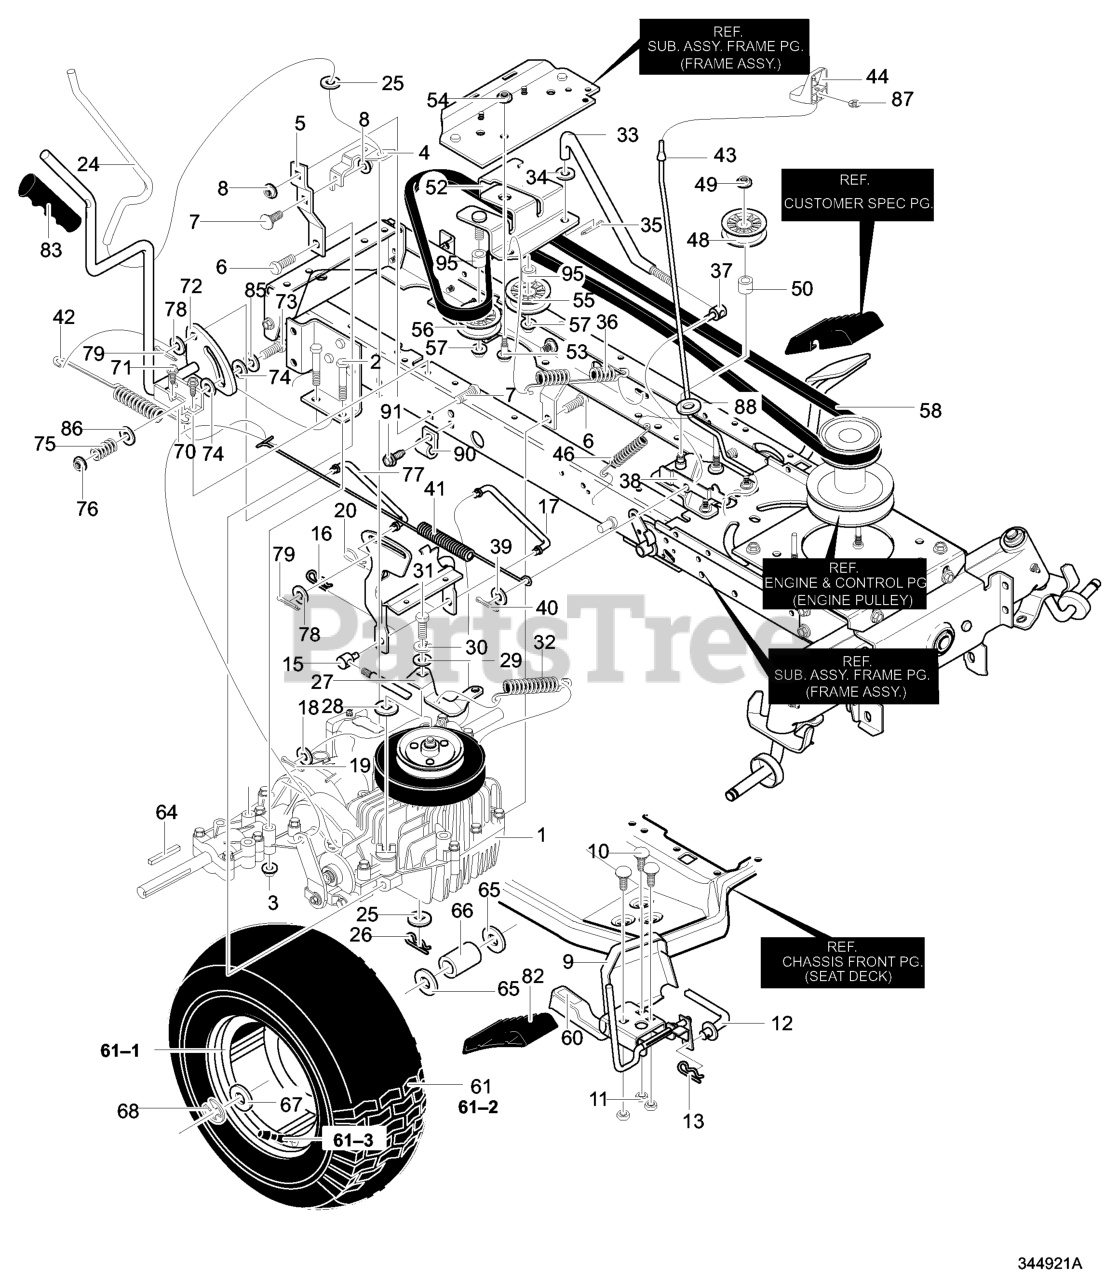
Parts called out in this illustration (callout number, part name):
1	Transaxle, Peerless **
2	SCREW, 5/16-18 x 2.50
3	NUT, 5/16-18
4	BRACKET, DISCONNECT
5	TORQUE STRAP -RIGHT
6	SCREW, 5/16-18 x 0.75
7	BOLT, CARRIAGE 5/16-18X .63
8	NUT, 5/16-18
9	WP, PEDAL ASSY HYDRO
10	BOLT, 5/16-18X .75
11	NUT, HEX 5/16-18
12	ROD, PEDAL LINK
13	PIN, HAIR
15	ADJUST NUT 1/2-13
16	PIN, HAIR
17	ROD HYDRO LINK
18	WASHER, FLAT
19	PIN, COTTER
20	PIN, HAIR
24	ROD, DISCONNECT
25	WASHER, FLAT
26	PIN, COTTER
27	ARM, DISCONNECT
29	WASHER, FLAT
30	WASHER
31	SCREW, 1/4-28 X.75
32	SPRING, EXTENSION
33	ROD, CLUTCH
34	WASHER, FLAT
35	PIN, COTTER
36	SPRING, CLUTCH
37	NUT, ADJUSTING
38	LATCH, PARKING BRAKE
39	WASHER, FLAT
40	PIN, COTTER
41	SPRING, EXTENSION
42	SPRING, EXTENSION
43	ROD- PARKING BRAKE
44	PARKING BRAKE KNOB
46	SPRING - EXTENSION
48	PULLEY, IDLER
50	SPACER 1/2 TO 17MM
52	ASSEMBLY, BRACKET IDLER
54	NUT, 3/8-16
55	PULLEY, IDLER
56	PULLEY, IDLER
57	NUT, 3/8-16
58	BELT, MOTION DRIVE HYDRO
60	PAD, TOE SANDPAPER
61	TIRE & RIM 23X9.50-12
61-1	VALVE STEM
64	KEY, SQUARE
65	WASHER, FLAT
67	WASHER, FLAT
70	BRACKET, HAND CONTROL
72	LEVER, HAND CONTROL
74	WASHER, FRICTION
75	SPRING - COMPRESSION
76	NUT, 5/16-18
77	LINK, CRUISE CONTROL
78	WASHER, FLAT
79	PIN, COTTER
82	PAD, SPEED CONTROL
85	WASHER, FLAT
86	WASHER, FLAT
87	PUSHNUT
88	WASHER, FLAT
90	RETAINER WIRE
95	SPACER 1/2 TO 17MM
